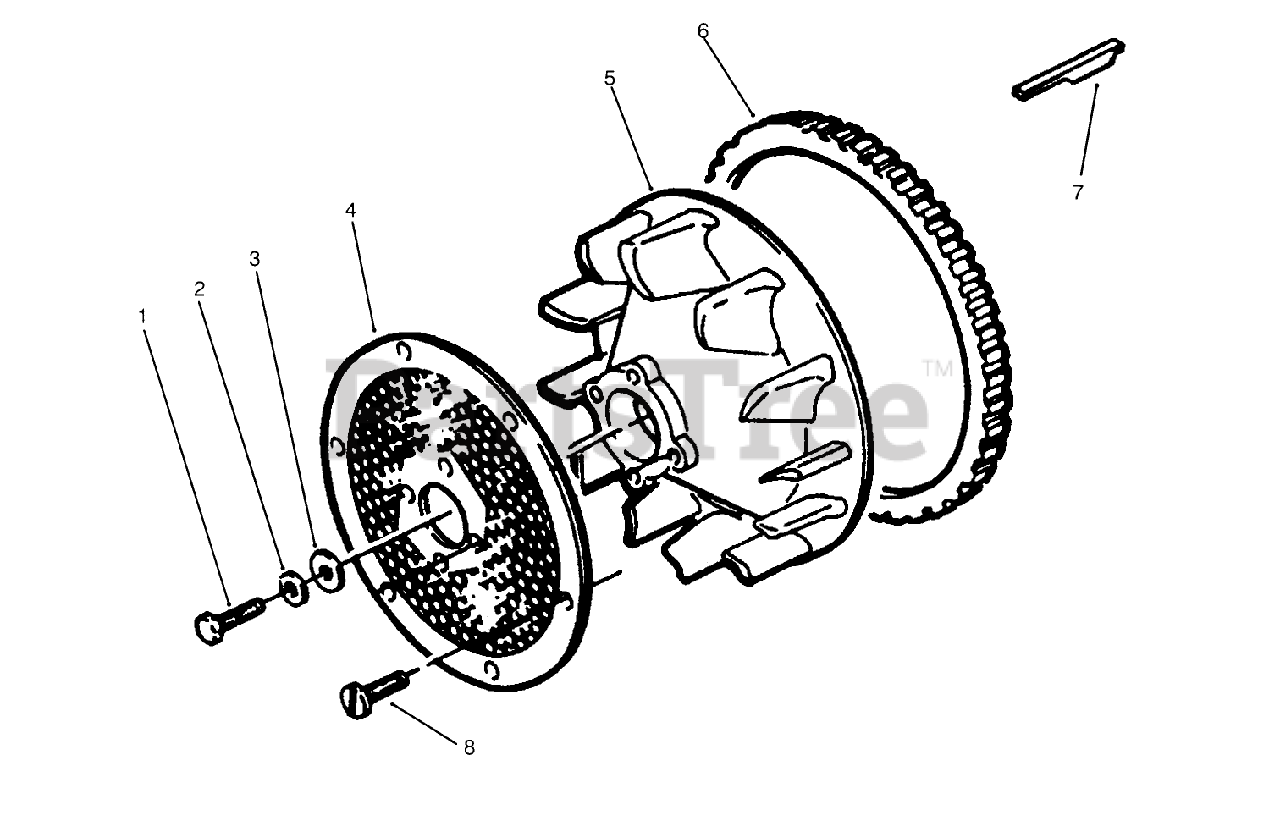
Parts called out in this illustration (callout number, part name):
2	WASHER-FLAT
3	WASHER-FLAT
4	SCREEN-AIR INLET
7	KEY-FLYWHEEL
